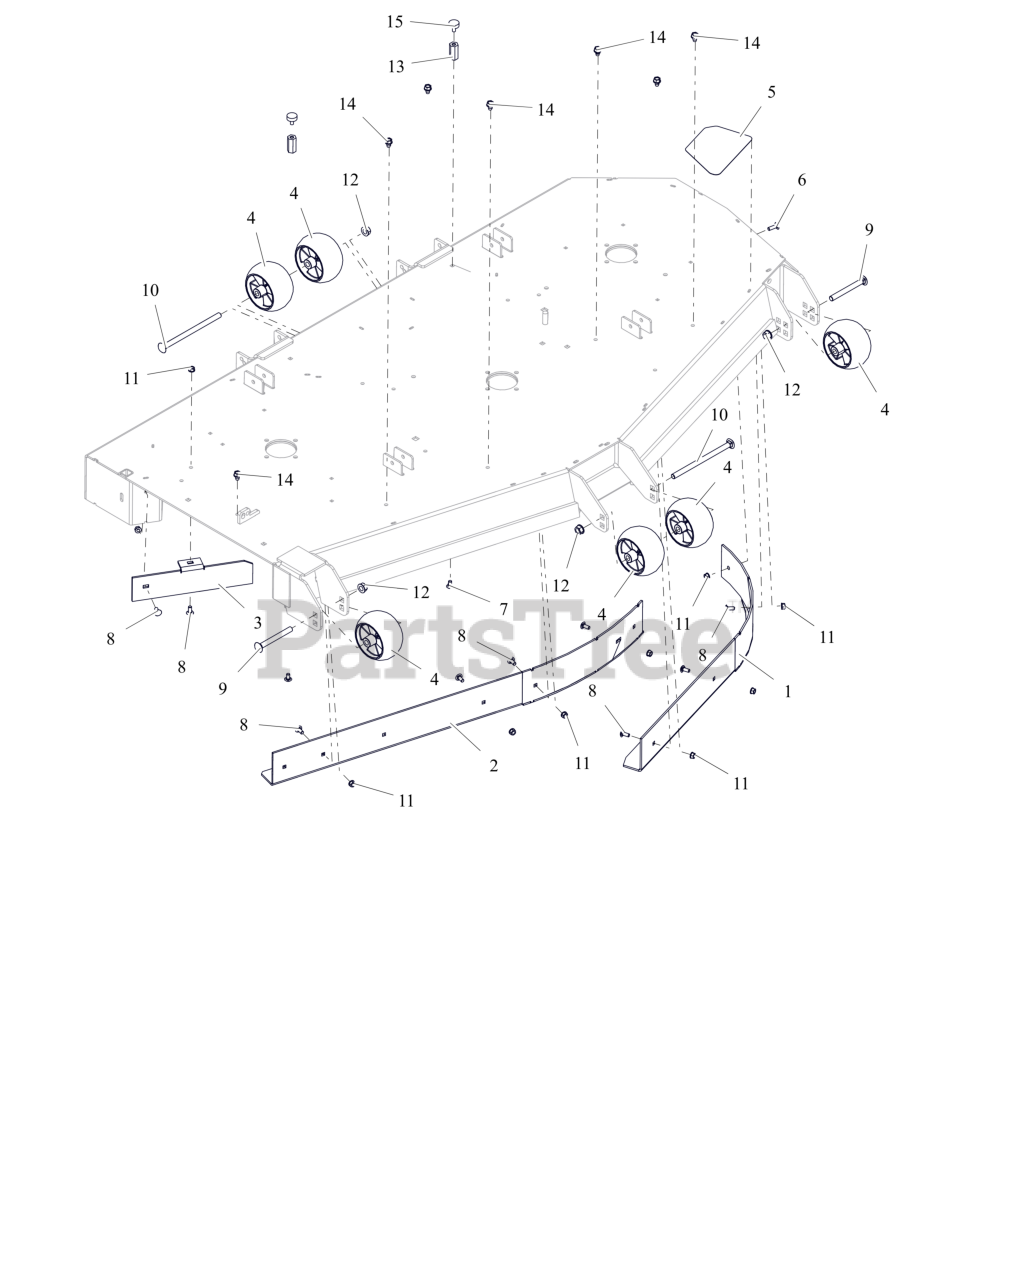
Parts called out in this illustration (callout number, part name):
1	WLDMT, 72" LH VACUUM BAFFLE (RED)
2	WLDMT, VACUUM BAFFLE 72" RH (RED)
3	72" DISCHARGE BAFFLE - RED
4	WHEEL, ANTI SCALP - 5X3 CTR W/RIBS
5	GRIP, STEP ANTI SKID
6	BLT,RHSSN .31-18X1.00 G5 ZCC
7	BTL,RHSSN .313-18 X 0.625 G5 ZCC
8	BLT, RHSSN.31-18X.750 G5 ZCC
9	BLT,RHNS .50-13X4.50 G5 ZCC NS
10	BLT,RHSN .50-13X8.00 G5 ZCC NS
11	NUT,LK-CTR-FLG .31-18 GF ZCC
12	NUT-LK-CTR-FLG .500-13 GG ZCC
13	NUT, COUPLING .312-18 X 1.625
14	SCR,TAP .375-16X.50 HWH TR ZCC
15	BUMPER, RUBBER
